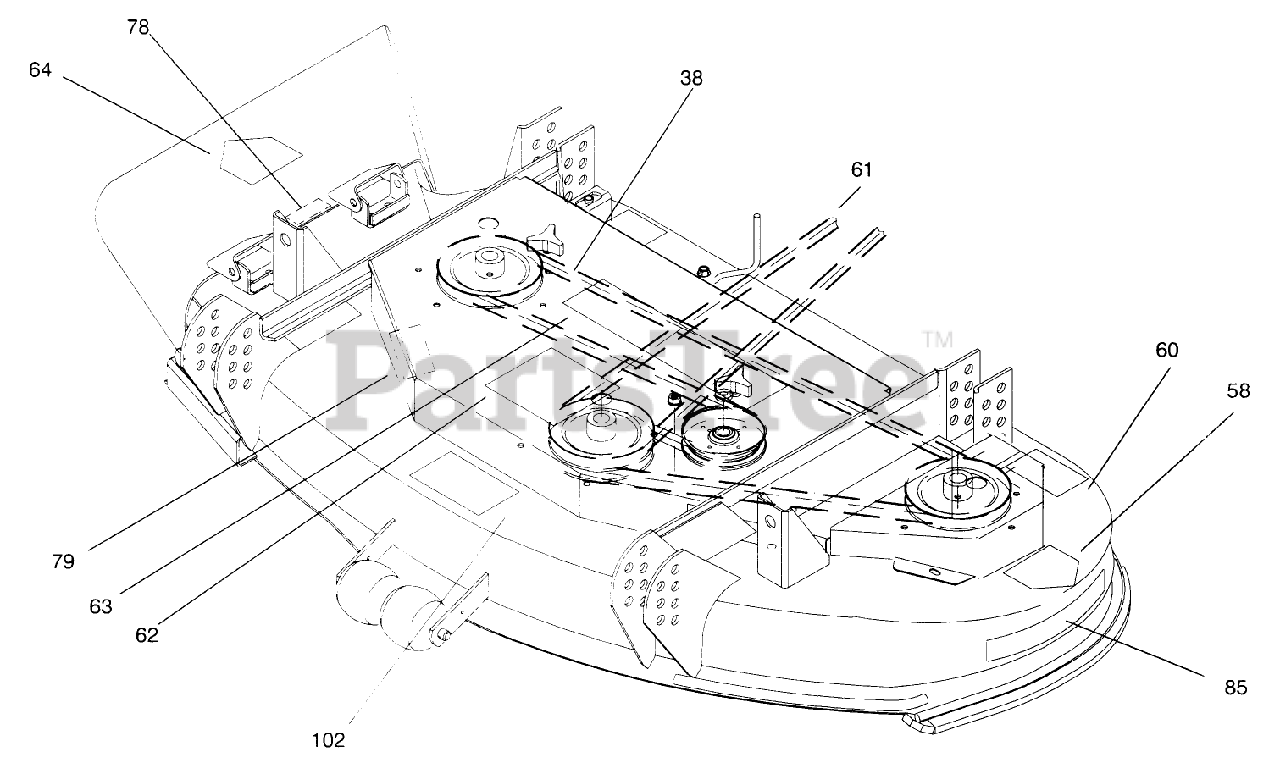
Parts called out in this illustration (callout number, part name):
38	Belt-Deck Drive
58	Decal-Danger
60	Decal-Torque
61	V-Belt (69.0)
62	Decal-44"
63	Decal-Proline
64	Decal-Danger
78	Decal-Danger
79	Decal-Danger
85	Decal-Recycler
102	Decal-Discharge
